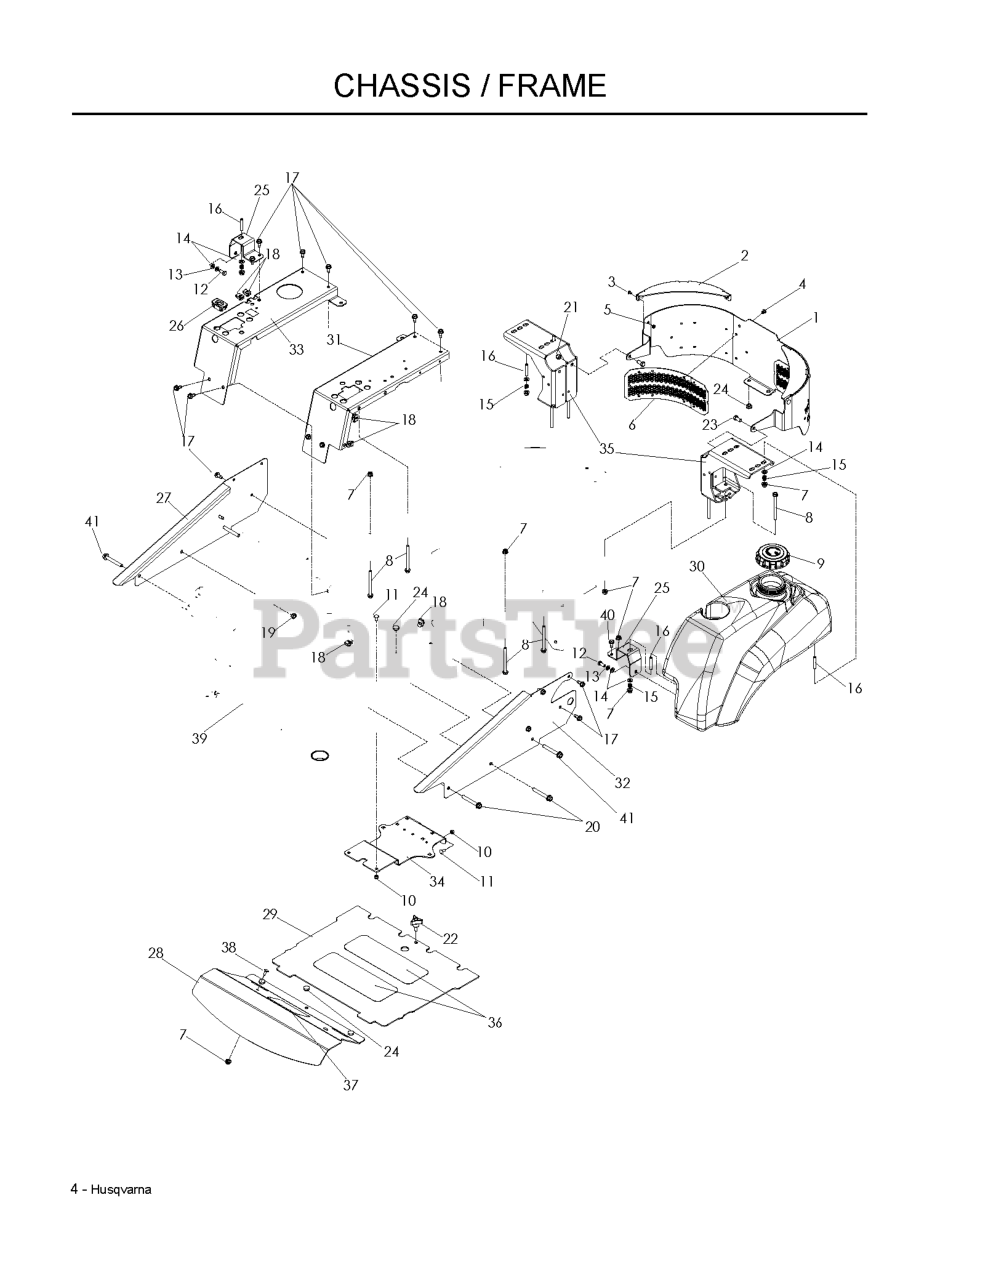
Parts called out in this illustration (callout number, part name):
1	GUARD, REAR
2	SUPPORT, TOP
3	RHSSNB 1/4-20 X 1/2
4	RIVERT, 3/16, STAVEX
5	JAM NUT 1/4C (2 2 PW01)
6	PANEL, HEX, RR
7	5/16-18 NYLOC FLANGE NUT
8	HHFS 5/16-18 X 3 3/4
9	FUEL CAP ANTI-SPLASH
10	NUT.1/4-20.HEX.NYLOC.ZD
11	RHSSNB, 1/4-20X5/8
12	HCS 5/16C X 3/4
13	WASHER.LOCK.HVY.HLCL.SPR.5/16
14	FLAT WASHER 5/16 SAE
16	STUD, 5/16C
17	BOLT 5/16-18 X 3/4
18	U-CLIP 5/16-18 NUT RETAINER
19	NUT HEX 3/8-16 NYLON, THIN
20	HHFS 3/8-16 X 2 3/4
21	NUT 3/8-16 NYLOC
22	KNOB W/STUD
23	SCREW 3/8C X 3/4 HEX CAP
24	GROMMET, BUMPER
25	SUPPORT, TANK, BLK
26	HOUR METER
27	SIDE.RT.ORANGE
28	PLATE, FOOTREST
29	PLATE, FLOOR W/DECALS
30	LEFT TANK W/CUP HOLDER
31	PANEL, FILLER, LT
32	SIDE.LT.ORANGE
33	PANEL, FILLER, RT
34	BATTERY MOUNT
35	MOUNT, TANK, RR
36	ANTI-SKID PAD
38	RHSNB 5/16C X 1
39	FRAME W/DECALS 52", 61"
40	RP BLT 5/16-18 X 1 THRD FORM D
41	HHFS 3/8-16 X 2.5 GR 5 ZD
